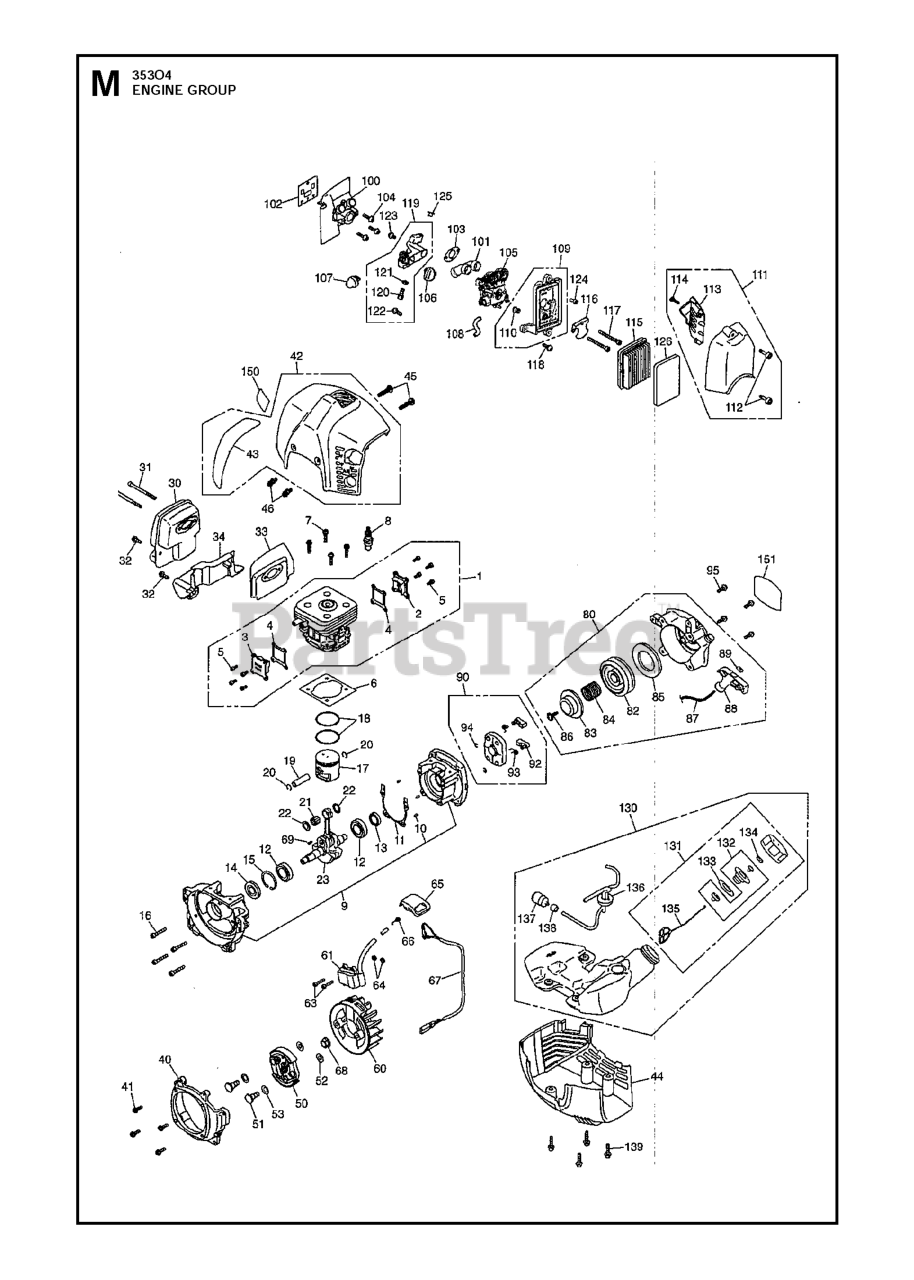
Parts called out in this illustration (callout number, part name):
4	GASKET, TR
7	BOLT
8	SPARK PLUG NGK CMR7H
16	BOLT
18	RING
19	PIN
23	CRANKSHAFT COMP
32	BOLT
45	SCREW, TORX (RPLS T4970-52001)
46	BOLT (RPLS T495051010-11)
68	NUT
69	KEY
85	SPRING, SPIRAL
94	E-RING
95	BOLT
104	BOLT, TORX
107	PUMP ASSY
118	BOLT
119	BRACKET ASSY
120	SCREW CABLE ADJUST
124	BOLT M4 X 12 T27
132	HOLDER-A
133	PACKING
134	FILTER
135	STOPPER
137	FILTER
